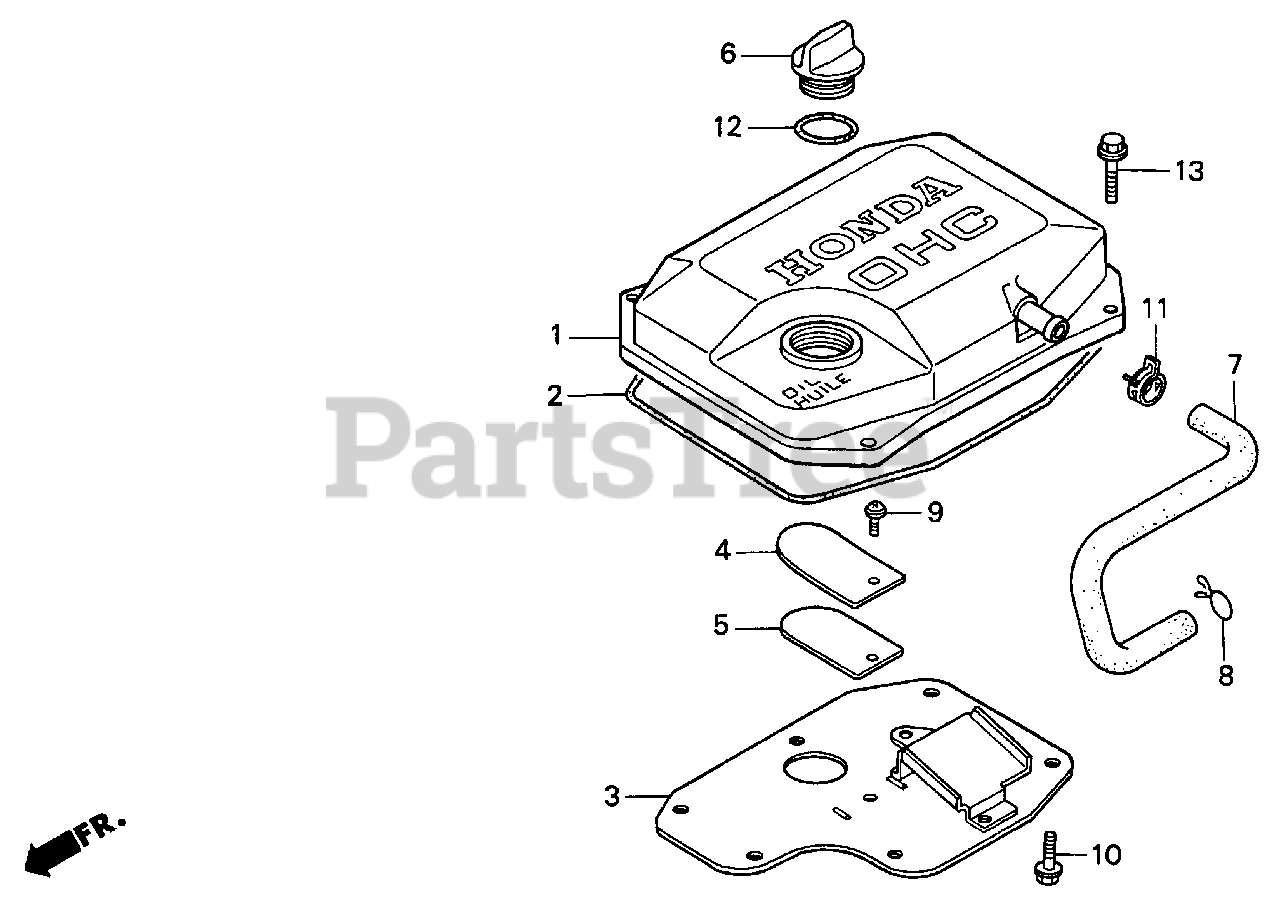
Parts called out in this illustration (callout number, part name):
1	COVER, CYLINDER HEAD
2	GASKET, HEAD COVER
3	COVER, BREATHER
4	STOPPER, VALVE
5	PLATE, VALVE
7	TUBE C, BREATHER
8	CLIP, BREATHER TUBE
9	SCREW-WASHER (5X8)
10	BOLT, FLANGE (6X10)
11	CLAMP, CANISTER HOSE
12	O-RING (26X2.7)
13	BOLT, FLANGE (6X25)
